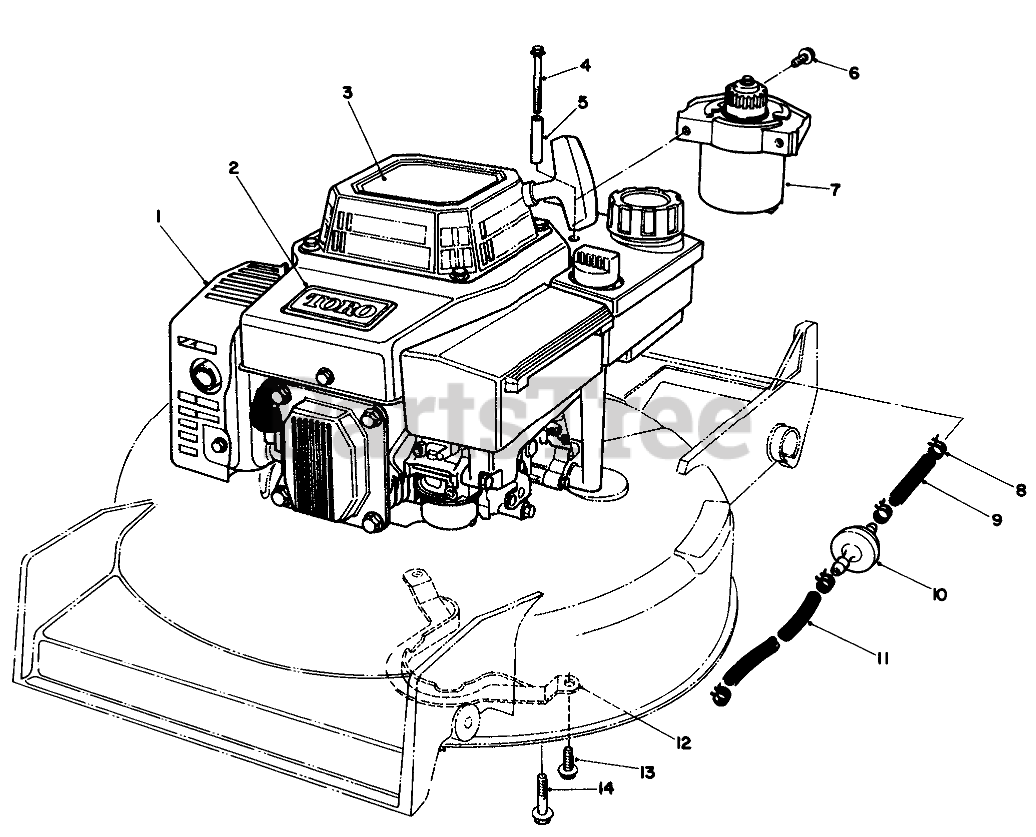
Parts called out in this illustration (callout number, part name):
1	Engine-Complete
2	TORO LOGO PLT
3	DECAL - RECOIL GTS
4	THRD FORMING SCREW
5	TUBULAR SPACER
6	SCREW
7	STARTER MOTOR ASM
8	CLAMP-FUEL LINE
9	LINE-GAS
10	FILTER-FUEL
11	HOSE-FUEL
12	BELT GUIDE
13	Screw
14	SCREW-HWHTF
